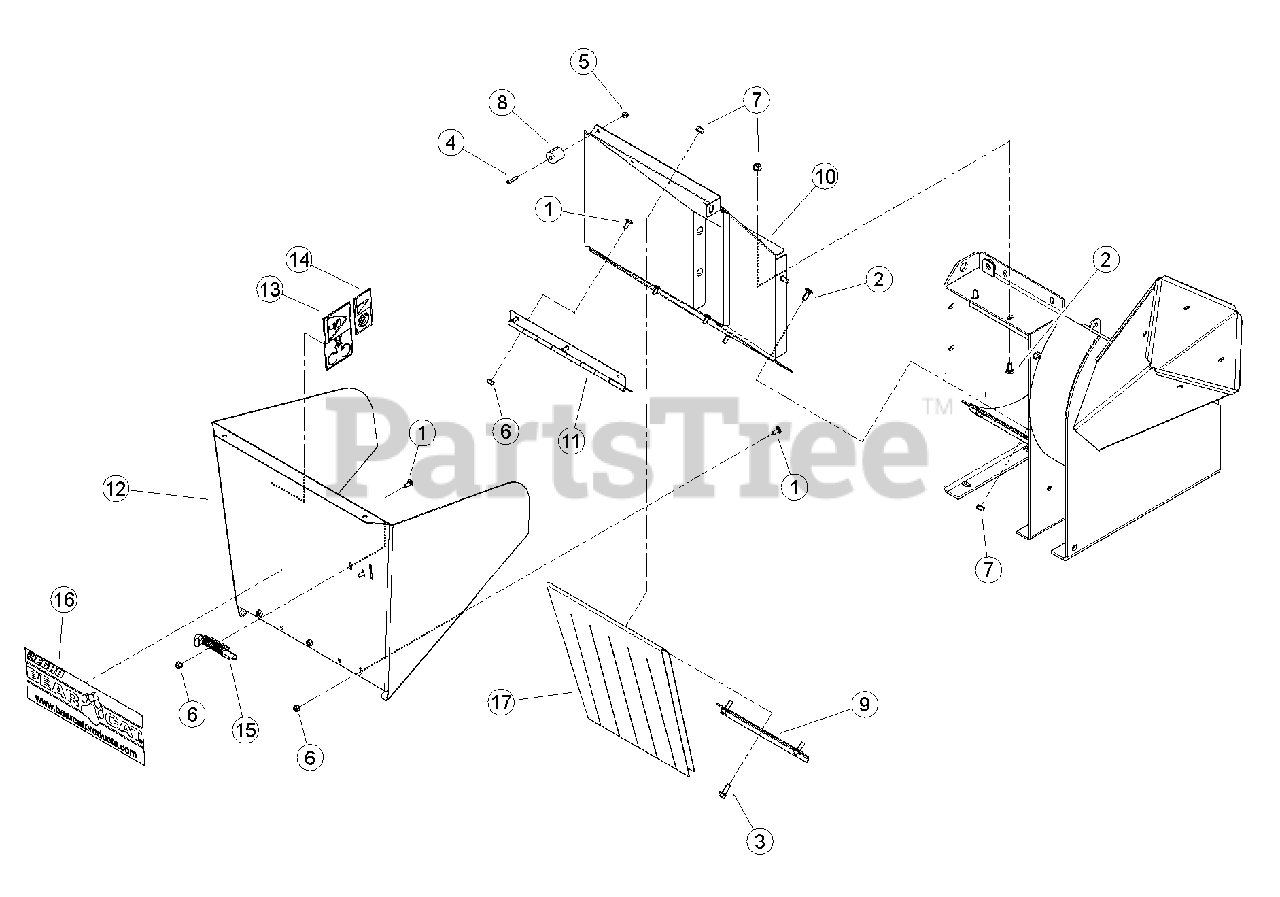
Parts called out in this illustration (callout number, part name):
1	BOLT, 5/16-18 X 3/4 CRG SN GR5
2	BOLT, 3/8 X 1" CRG GR5 NC ZP
3	BOLT, 3/8 X 1 FLANGE NC
4	BOLT, 1/4 X 1 SOC HD CAP SCRW
5	NUT, 1/4-20 NYLOCK-FLANGE
6	NUT, 5/16-18 NYLOCK-FLANGE
7	NUT, 3/8-16 NYLOCK-FLANGE
8	BUMPER, RECESSED RUBBER
9	ANGLE, FLAP ANCHOR
10	WELDMENT, CHUTE
11	HINGE, EXTENSION TRAY
12	ASSEMBLY, EXTENSION TRAY
13	DECAL, BLADE DANGER ISO
14	DECAL, SHREDDER SIZE ISO
15	LATCH, RH HINGE
16	DECAL, BEARCAT WEB
17	FLAP, C/S/B CHUTE
